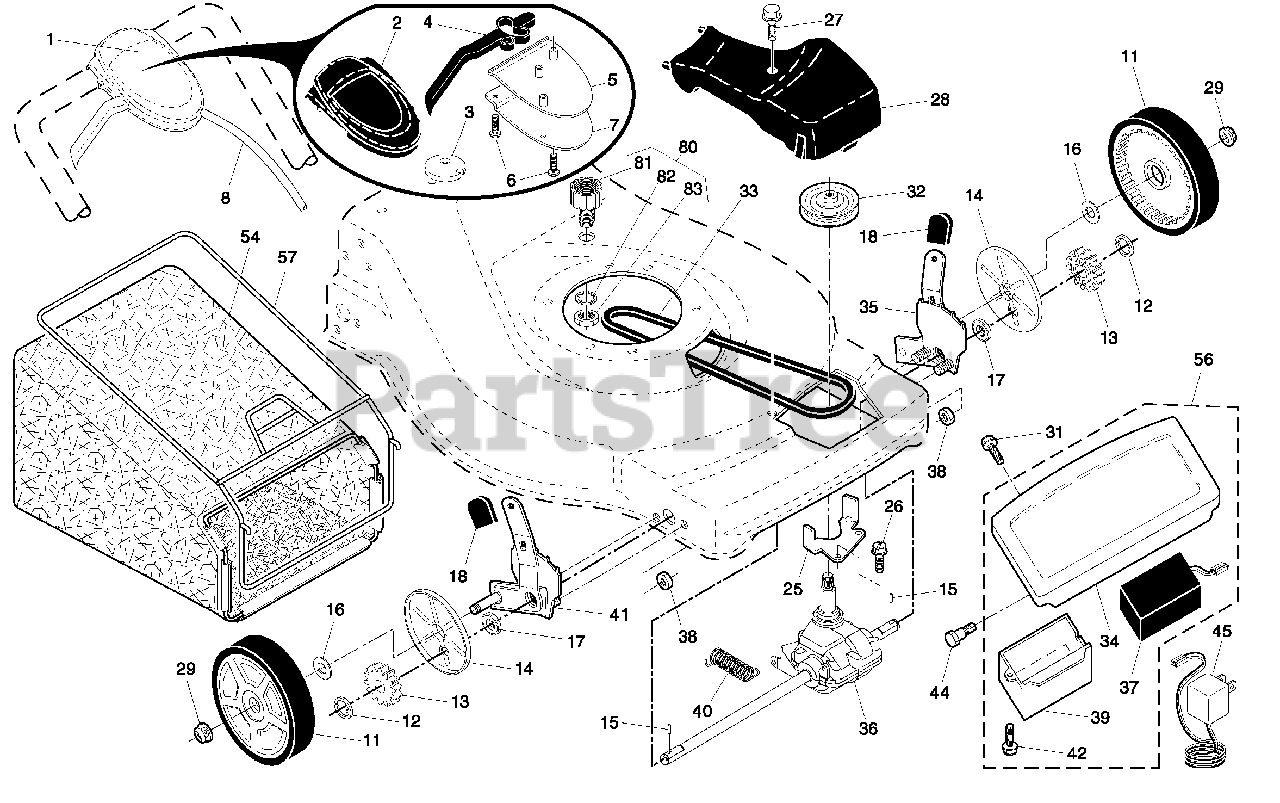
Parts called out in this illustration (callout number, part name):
1	Drive Control Assembly
2	Cover, Drive Control, Top
3	Pulley
4	Lever, Drive Control
5	Cover, Drive Control, Bottom
6	Screw, Torx Head #8 x 5/8
7	Mounting Bracket, Drive Control
8	Cable, Drive Control
11	Wheel & Tire Assembly
12	E-Ring
13	Gear, Pinion
14	Dust Cover
15	Pawl, Drive
16	Washer, Flat 3/8
17	Bearing, Wheel Adjuster
18	Selector Knob
25	Belt Keeper
26	Screw, Hi-Lo Thread
27	Pan Head Tapping Screw #10-24 x 2-3/4
28	Drive Cover
29	Locknut, Hex
31	Screw, Trimplate
32	Drive Pulley
33	V-Belt
34	Trimplate
35	Kit, Wheel Adjuster, LH
36	Gearcase Assembly, Complete
37	Battery
38	Locknut, Hex 1/4-20
39	Battery Box
40	Spring
41	Kit, Wheel Adjuster, RH
42	Screw, Battery Box
44	Screw, Trimplate
45	Charger, Battery
54	Grassbag Assembly
56	Trimplate, Battery Box and Battery Assembly
57	Frame, Grassbag
80	Kit, Water Washout
81	Fitting, Hose, Water Washout
82	Washer, Lock, Internal Tooth
83	Locknut, Hex, with O-Ring
